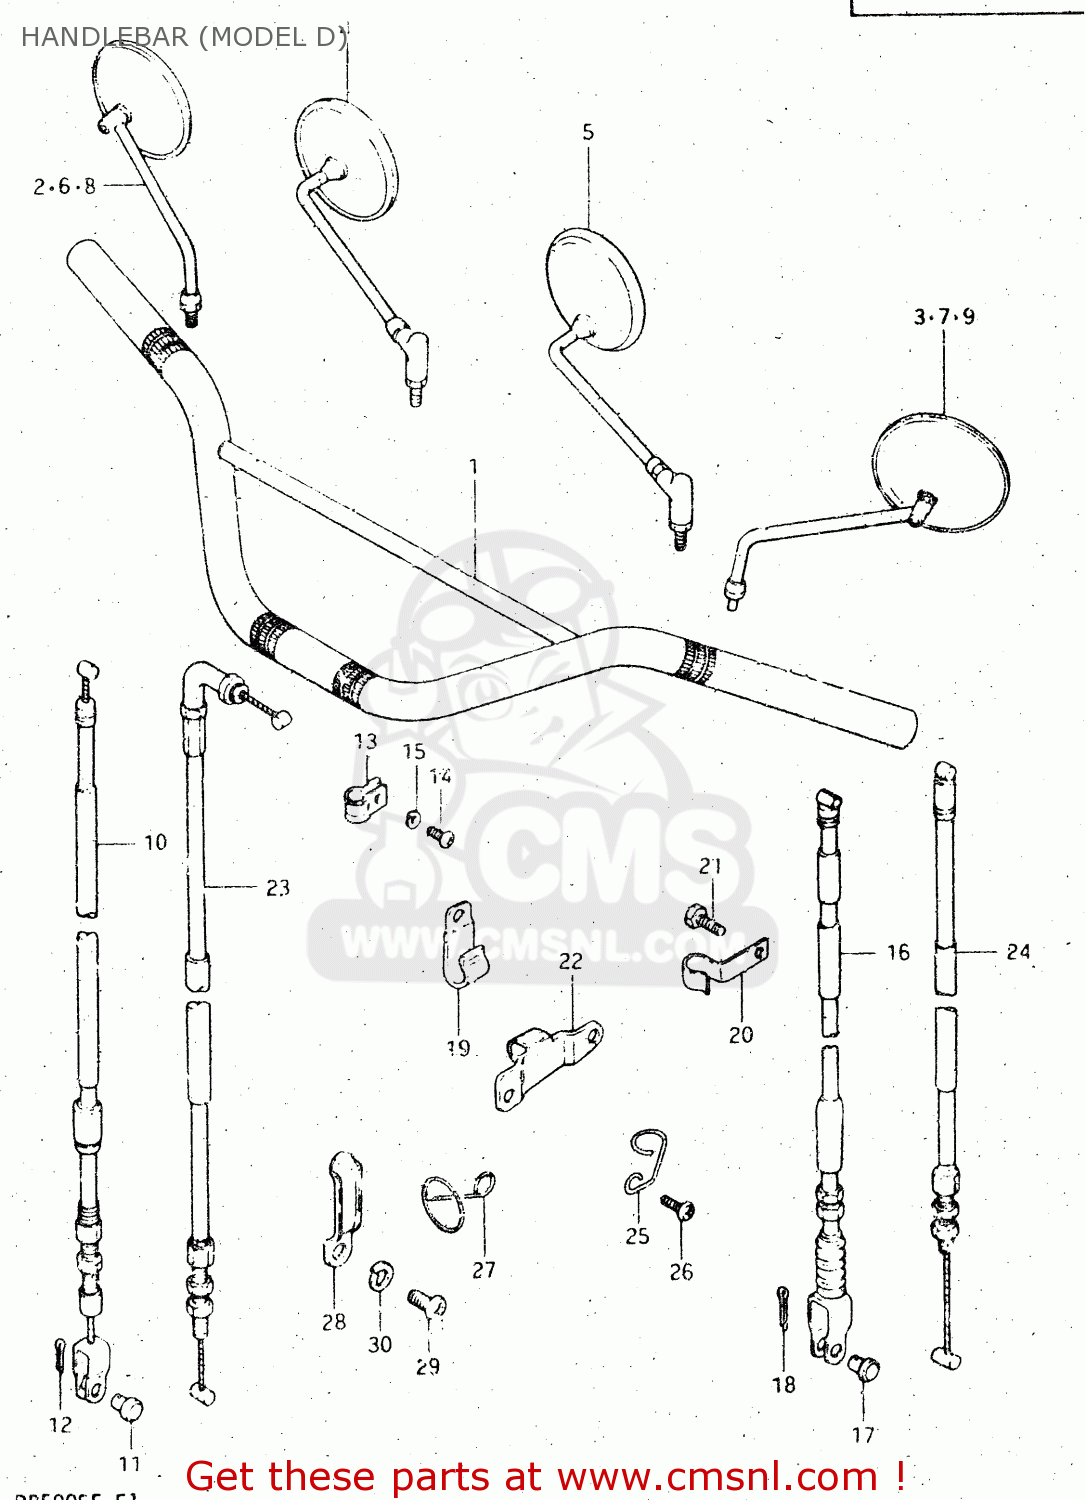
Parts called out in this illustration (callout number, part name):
1	HANDLEBAR (BLACK)
2	MIRROR ASSEMBLY,RIGHT
3	MIRROR ASSEMBLY,LEFT
4	MIRROR ASSY,RH
5	MIRROR ASSY,RH
6	MIRROR ASSY,RR VIEW,R
7	MIRROR, REAR VIEW LH
8	MIRROR ASSY RH
9	MIRROR ASSY
10	CABLE ASSEMBLY,FRONT BRAKE
11	PIN(L:17.5)
12	PIN
13	GUIDE,CABLE
14	SCREW
15	LOCK WASHER
16	CABLE ASSEMBLY,CLUTCH
17	PIN(L:15)
18	PIN
19	CLAMP
20	CLAMP,CLUTCH CABLE NO.1
21	BOLT
22	STOPPER,CLUTCH CABLE
23	CABLE ASSY,THROTTLE
24	CABLE ASSY,DECOMP
25	GUIDE
26	SCREW
27	GUIDE,CABLE
28	CLAMP
29	SCREW
30	LOCK WASHER
